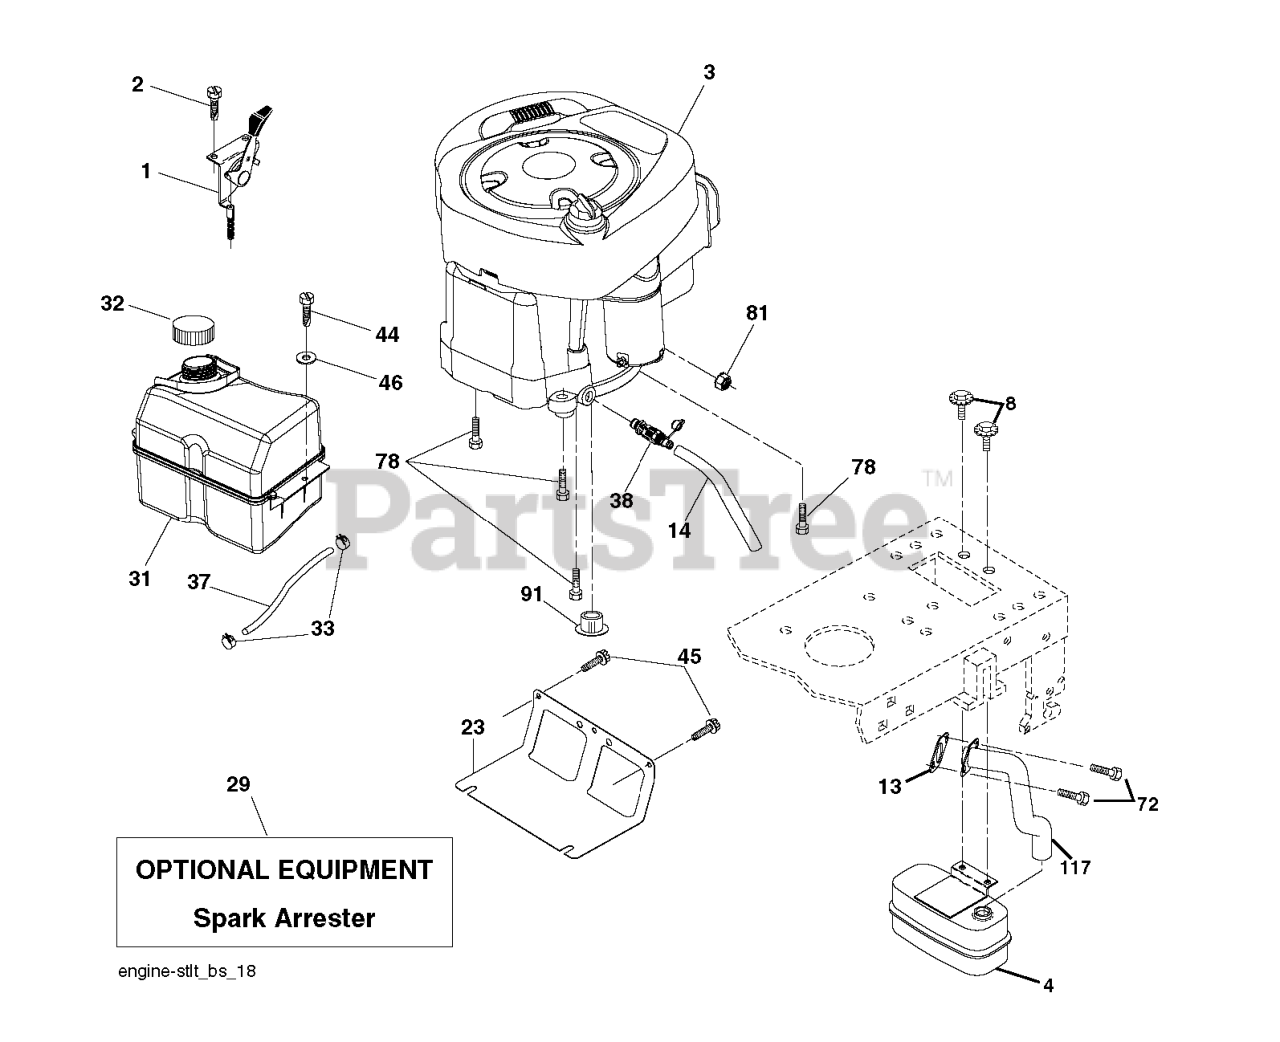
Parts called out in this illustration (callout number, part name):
1	CONTROL.TH/CK.C.
2	SCREW.#10 X 0.750.BOS
4	MUFFLER.SINGLE.CYL.KOHL/B&S
8	BOLT.5/16-18UNCX3/4 W/SEMS.BLK
13	REPL BY 532 27 22-93
14	TUBE, DRAIN OIL ASM.
23	SHIELD.BROWNING.DBR.GUARD
29	KIT.SPARK ARRESTOR 794945 B&S
31	RP TANK FUEL FRT 1.5 GAL
32	CAP ASM.FUEL.2.25"FR.
33	HOSE CLAMP
37	LINE.FUEL.20
38	VALUE.OIL.DRAIN
44	SCREW HEXWSHR 1/4-20X3/4
45	SCREW, 3/8-16X3/4
72	SCREW.SOCKET HD.5/16-1
78	SCREW.3/8-16
81	NUT
91	BUSHING.1.375OD
117	EXHAUST.TUBE.B&S.
